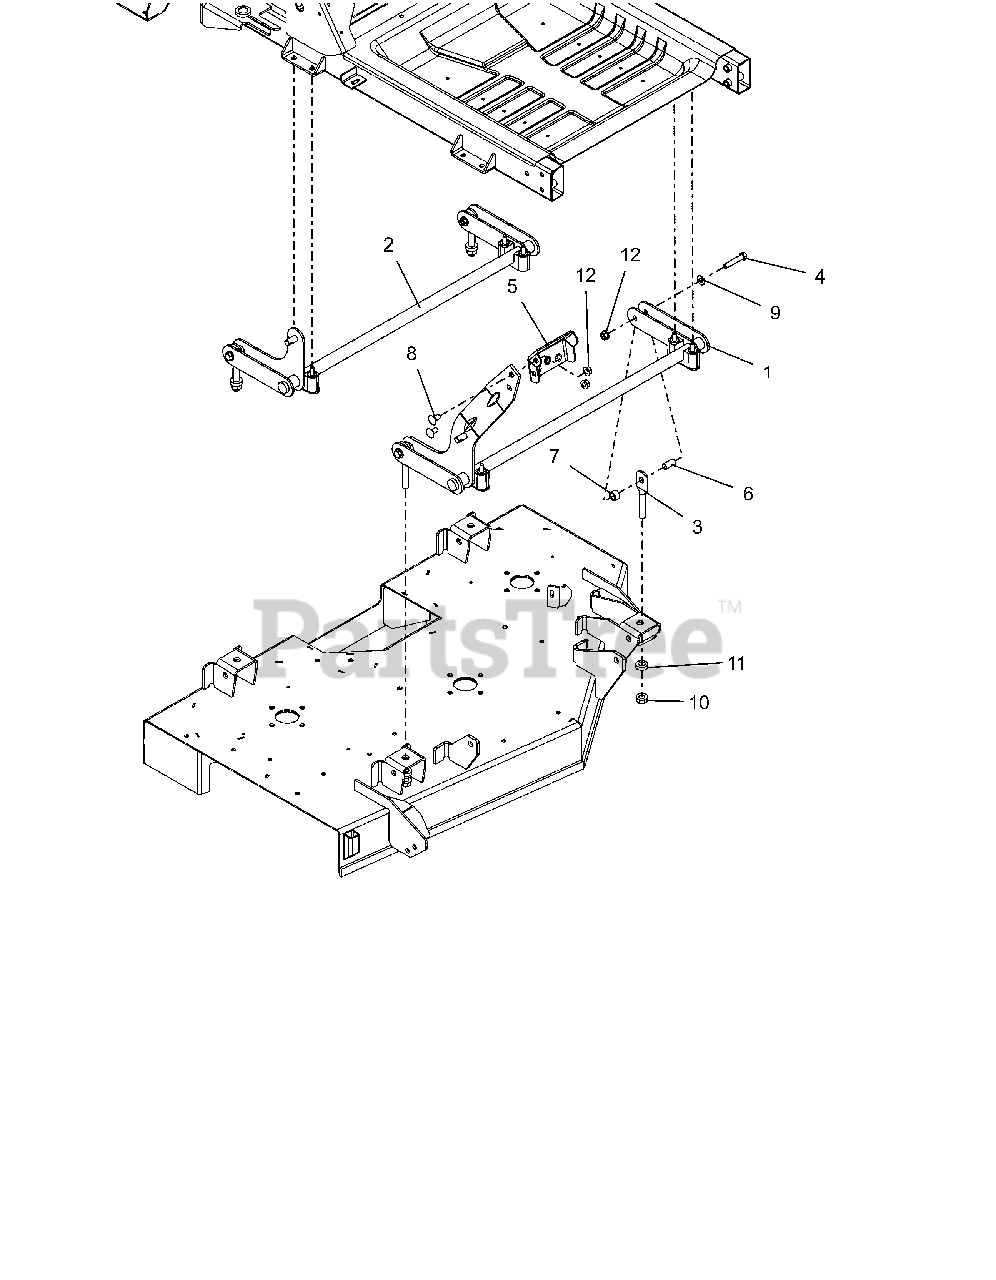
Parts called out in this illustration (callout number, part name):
1	WLDMT, FRONT DECK LIFT PIVOT
2	WLDMT, REAR DECK PIVOT
3	LINK, DECK (HOLE-SHORT)
4	BLT, HEX .38-16X2.00 G8 ZCC
5	PEDAL, DECK LIFT (BOLT ON)
6	BSHG-SLV .385X.500X1.045
7	BSHG-SLV .510X.751X.475
8	BLT,RHSN .38-16X.75 G5 BFP
9	WSHR,FLT .406X.812X.065 ZCC
10	NUT-LK-CTR-FLG .500-13 GG ZCC
11	WSHR, RUBBER
12	NUT-LK-CTR-FLG .375-16 GF ZCC
